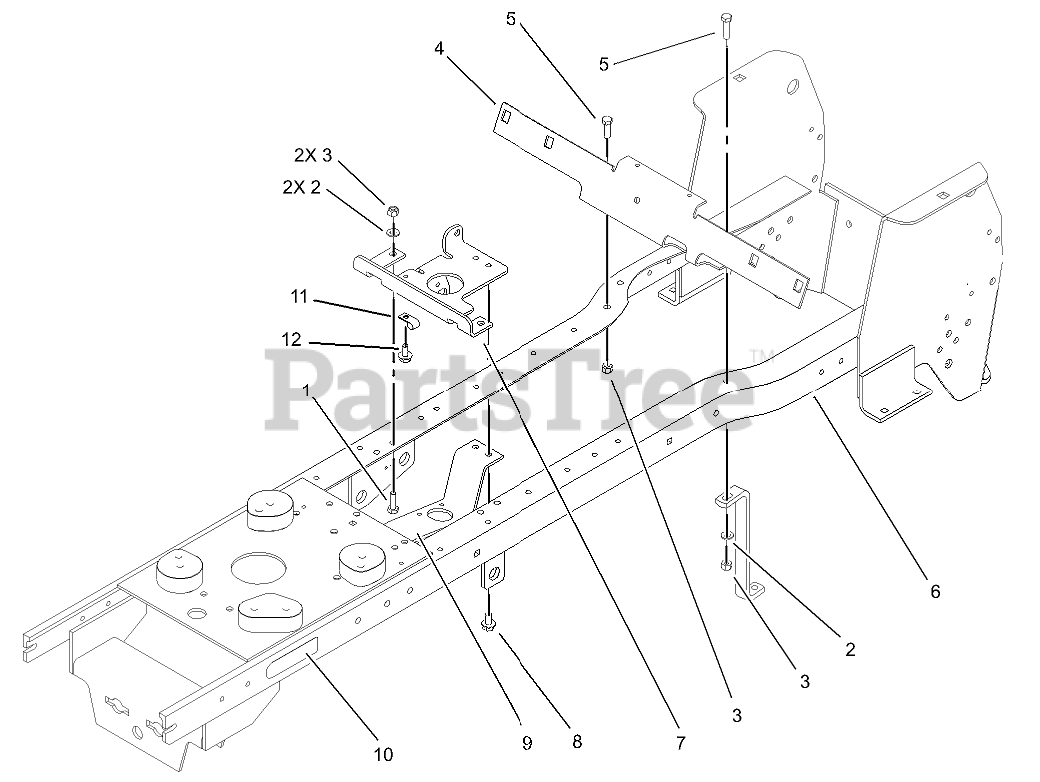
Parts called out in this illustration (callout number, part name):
1	SCREW-HH
2	WASHER-PLAIN
3	NUT-LOCK, NI
4	SUPPORT-FENDER
5	SCREW-HH
6	FRAME ASM
7	BRACKET-SUPPORT, STEERING
8	SCREW-HWHTF
9	STEERING BRACKET ASM
10	DECAL-ATTACH A-MATIC
11	CLAMP-R
12	SCREW-HWH
